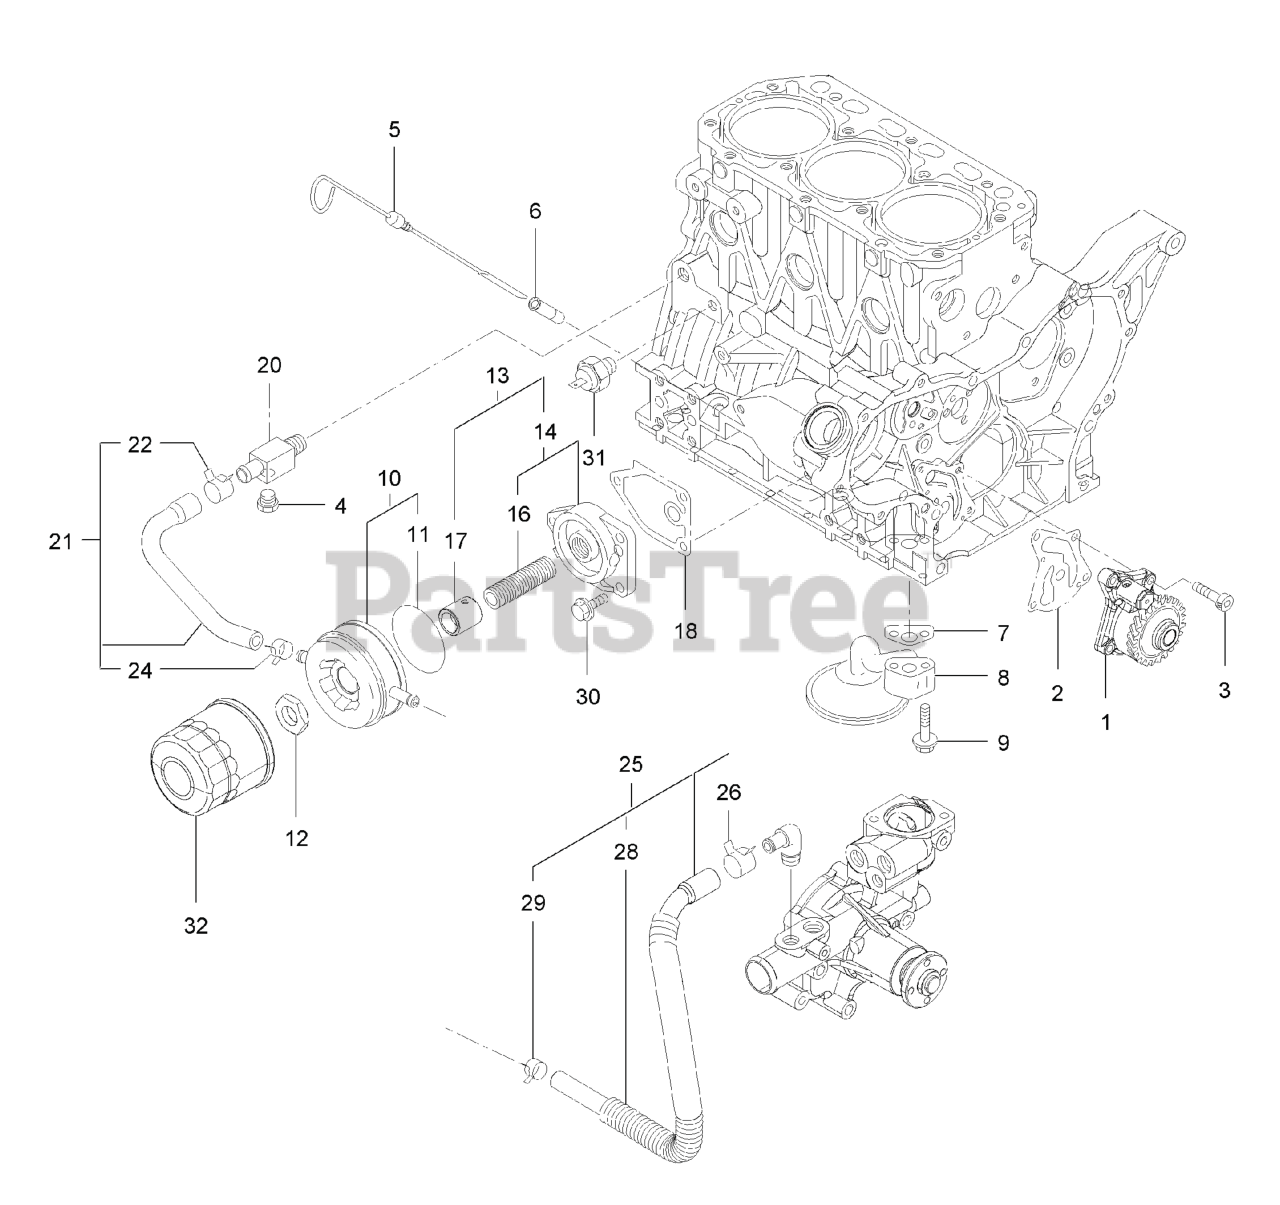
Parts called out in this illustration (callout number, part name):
1	OIL PUMP ASM
4	PLUG-DRAIN
5	DIPSTICK
6	GUIDE-DIPSTICK
8	PIPE ASM-OIL INLET
10	COOLER ASM-OIL
11	PACKING-OIL COOLER
13	BRACKET ASM-LO FILT
14	BRACKET ASM
17	COLLAR-OIL COOLER
21	PIPE ASM
24	CLAMP-HOSE
25	PIPE ASM
29	CLAMP-HOSE
31	SWITCH-OIL
32	FILTER-ENGINE
